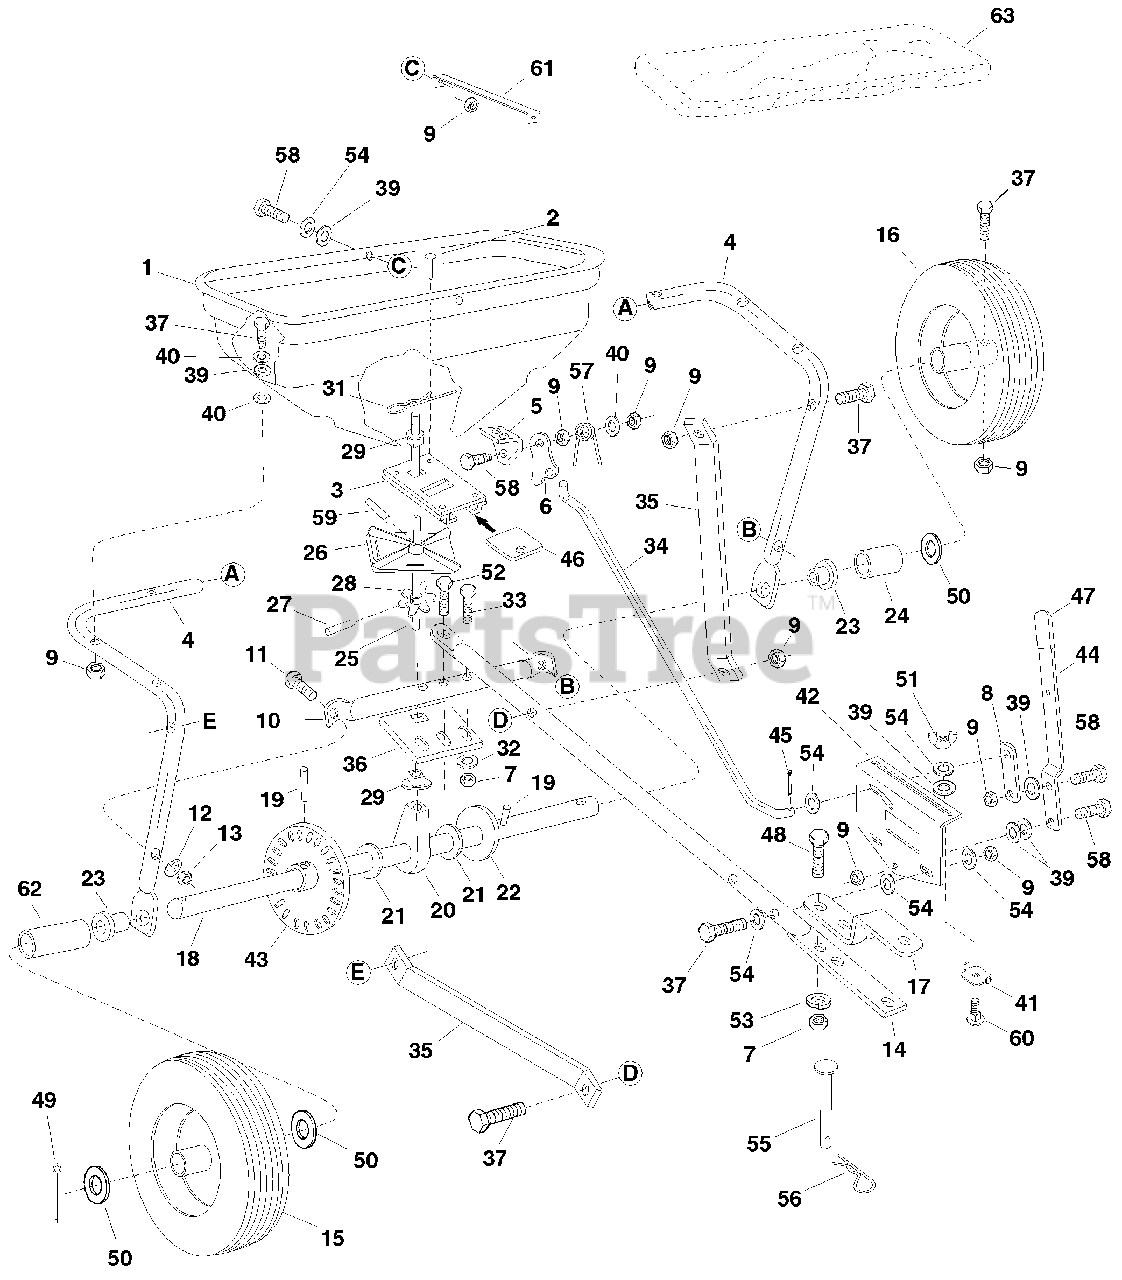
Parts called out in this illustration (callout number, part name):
2	Rivet, Stainless
3	Ass'y, Guide Closure
4	Tube, Frame
5	Slide Gate Angle Bracket
6	Slide Gate Bracket
7	Nut, Hex Lock 3/8-16 Thd.
8	Flow Control Link
9	Nut, Hex Lock 1/4-20 Thd.
10	Tube, Crossover
11	Bolt, Hex 5/16-18 x 1-3/4" Lg.
12	Lock Washer, 5/16"
13	Nut, Hex Lock, 5/16-18 Thd.
14	Tube, Hitch
15	Wheel, Idler
16	Wheel, Drive
17	Bracket, Hitch
18	Shaft, Axle
19	Pin, Spring 3/16" Dia. x 1-1/4" Lg.
20	Bushing, Axle Shaft
21	Washer, Flat .78 I.D.
22	Washer, Flat 1/2"
23	Bearing, Flange
24	Spacer Tube
25	Shaft, Sprocket
26	Spreader Plate
27	Pin, Spring 1/8" Dia. x 5/8".
28	Sprocket, 6 Tooth
29	Bushing, Delrin
31	Hairpin, Agitator
32	Washer, Flat 3/8"
33	Bolt, Hex 3/8-16 x 1-3/4" Lg.
34	Rod, Flow Control
35	Brace, Hitch
36	Shaft Support Plate
37	Bolt, Hex 1/4-20 x 1-3/4"
39	Washer, Nylon
40	Washer, Flat 1/4" Std.
41	Stop, Adjustable
42	Bracket, Flow Control Mount
43	Gear Assembly
44	Flow Control Arm
45	Cotter Pin 3/32" x 3/4" Lg.
46	Plate, Closure
47	Grip, Flow Control Arm
48	Bolt, Hex 3/8-16 x 1-1/4" Lg.
49	Pin, Cotter 1/8" x 1-1/2"
50	Washer, Flat 1-5/8" O.D.
51	Wing Nut, Nylon
52	Bolt, Hex 3/8-16 x 2" Lg.
53	Lock Washer, 3/8"
54	Washer, 5/16 SAE
55	Hitch Pin
56	Hair Cotter Pin, 1/8"
57	Spring, Torsion
58	Bolt, Hex 1/4-20 x 3/4" Lg.
59	Pin, Spring 1/8" Dia. x 1" Lg.
60	Bolt, Carriage 1/4-20 x 3/4"
61	Strap, Hopper
62	Spacer Tube
63	Vinyl Cover
